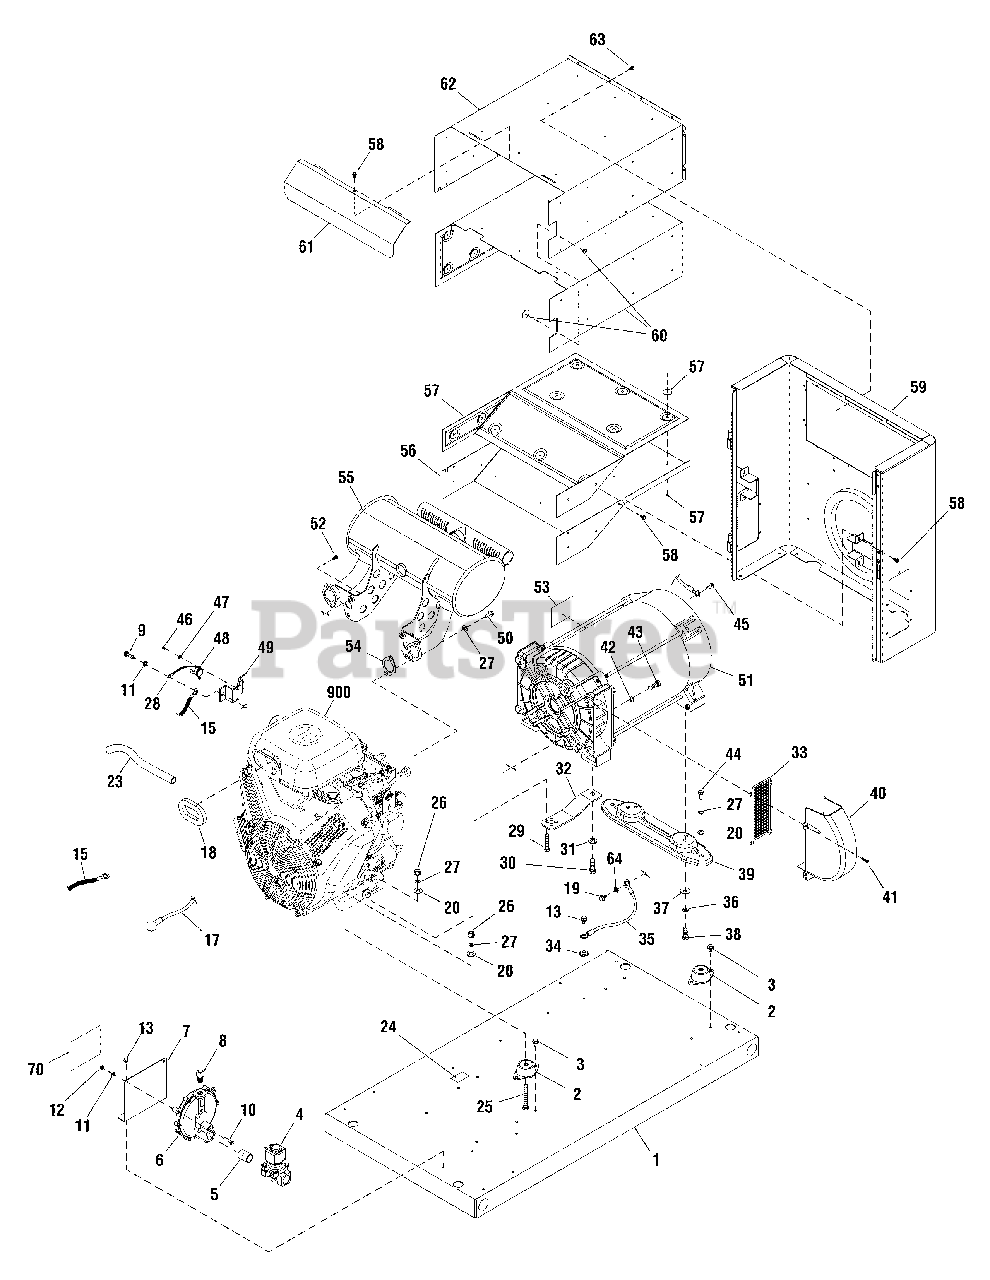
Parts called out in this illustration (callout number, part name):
2	MOUNT-VIBRATION
4	SOLENOID-GAS FUEL
6	REGULATOR-NG/LPG
7	BRACKET
9	* CAPSCREW, Hex Head, M6-1.0 x 16
10	* CAPSCREW, Hex Head, M6-1.0 x 30
11	* WASHER, Lock, 1/4
12	* NUT, M6-1.0
13	BOLT
18	TUBE
20	* WASHER, Flat, 5/16 (M8)
24	DECAL-OIL DRAIN
25	* CAPSCREW, Hex Head, 5/16-18 x 2.5
26	* NUT, 5/16-18
27	* WASHER, Lock 5/16 (M8)
29	* CAPSCREW, Hex Head, 5/16-18 x 2
30	* CAPSCREW, Hex Head, M12-1.75 x 35
31	* WASHER, M12
34	* WASHER, Shakeproof, M6-1/4
36	* WASHER, Lock, 3/8
37	* WASHER, Flat, 3/8
38	* CAPSCREW, Hex Head, 3/8-16 x 1
39	SUPPORT-ALTERNATOR
41	* SCREW, Taptite, M5.8 x 10
42	* WASHER, Lock, 3/8
43	* CAPSCREW, Socket Head, 3/8-16 x 1-1/4
44	* CAPSCREW, Hex Head, 5/16-18 x 3/4
45	BOLT
46	* PPHMS-4-40 x 0.19
47	* WASHER, Lock, #4
49	PLATE-TEMP SWITCH
50	SCREW
51	ALTERNATOR
53	DECAL
59	BULKHEAD-ALTERNATOR
62	BOX-MUFFLER TOP
64	* WASHER, Shakeproof, M6
900	** ENGINE
